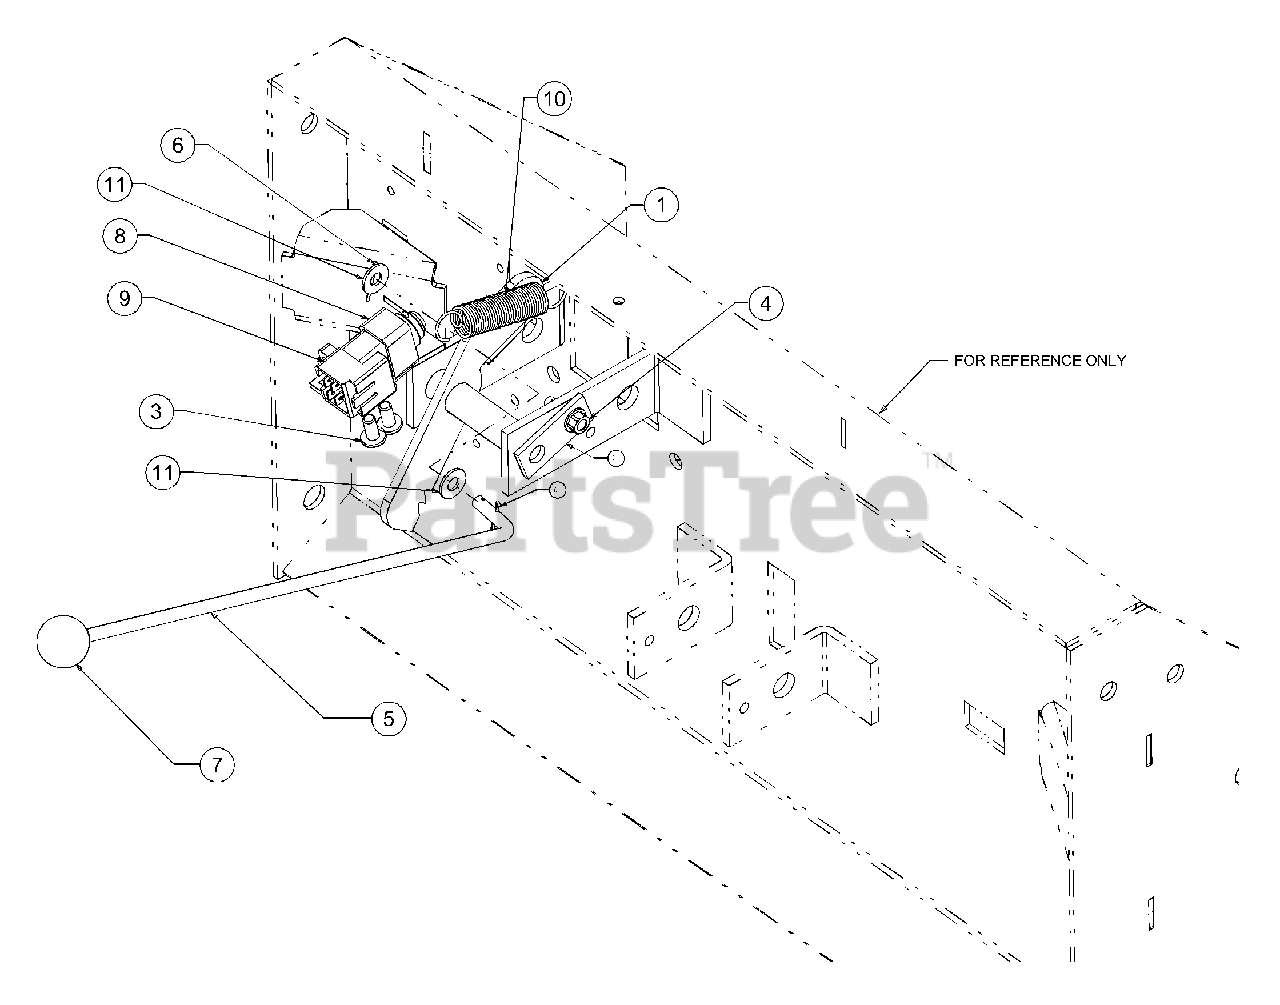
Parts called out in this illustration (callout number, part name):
1	Lever Assembly, Parking Brake
2	Shaft Assembly, Pedal Pivot
3	Screw, Hi-Lo, 1/4-20 x .5
4	Screw, Self-tapping, 1/4-20, .75
5	Rod, Brake Lock
6	Pin, Cotter 1/16 x .75
7	Knob, Ball
8	Cover, Protective
9	Snap Mount Switch, Interlock
10	Spring, Extension, .637 x 2.972
11	Washer, Flat .25 x .630 x .0515
